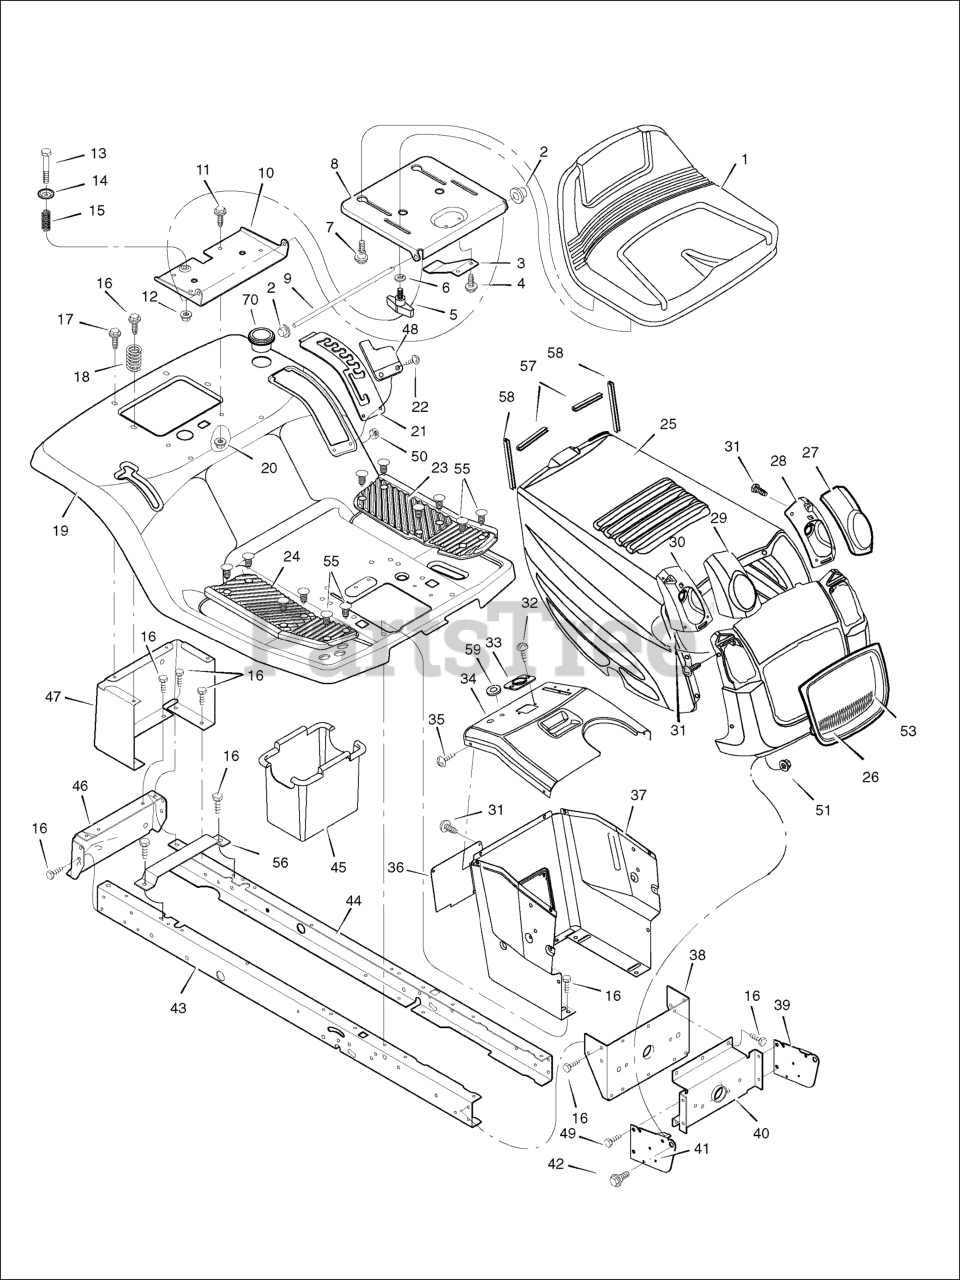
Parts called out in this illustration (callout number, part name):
1	Seat
2	Cap, Push 0n
5	Bolt, Wing
6	Washer
7	Bolt, Shoulder
8	Support, Seat
9	Rod, Pivot
10	Bracket, Pivot
11	Bolt
13	Bolt, Shoulder
20	Nut
21	Plate, Index
23	Mat, Left
24	Mat, Right
25	Hood
27	Lens, Left
28	Housing, Left Headlamp
29	Lens, Right
30	Housing, Right Headlamp
33	Bearing, Steering
34	Dash
36	Panel, Access
37	Support, Dash
38	Bracket, Rear Hanger
39	Support, Left Grille
40	Axle, Hanger
41	Support, Right Grille
42	Bolt, Shoulder
43	Frame, Right
44	Frame, Left
45	Container, Battery
46	Plate, Hitch
47	Panel, Rear
48	Cover, Detent
53	Insert, Grille
55	Fastener, Panel
56	Support, Battery
57	Trim, Hood (3.75")
58	Trim, Hood (6.5")
59	Grommet, Parking Brake
70	Holder, Cup
